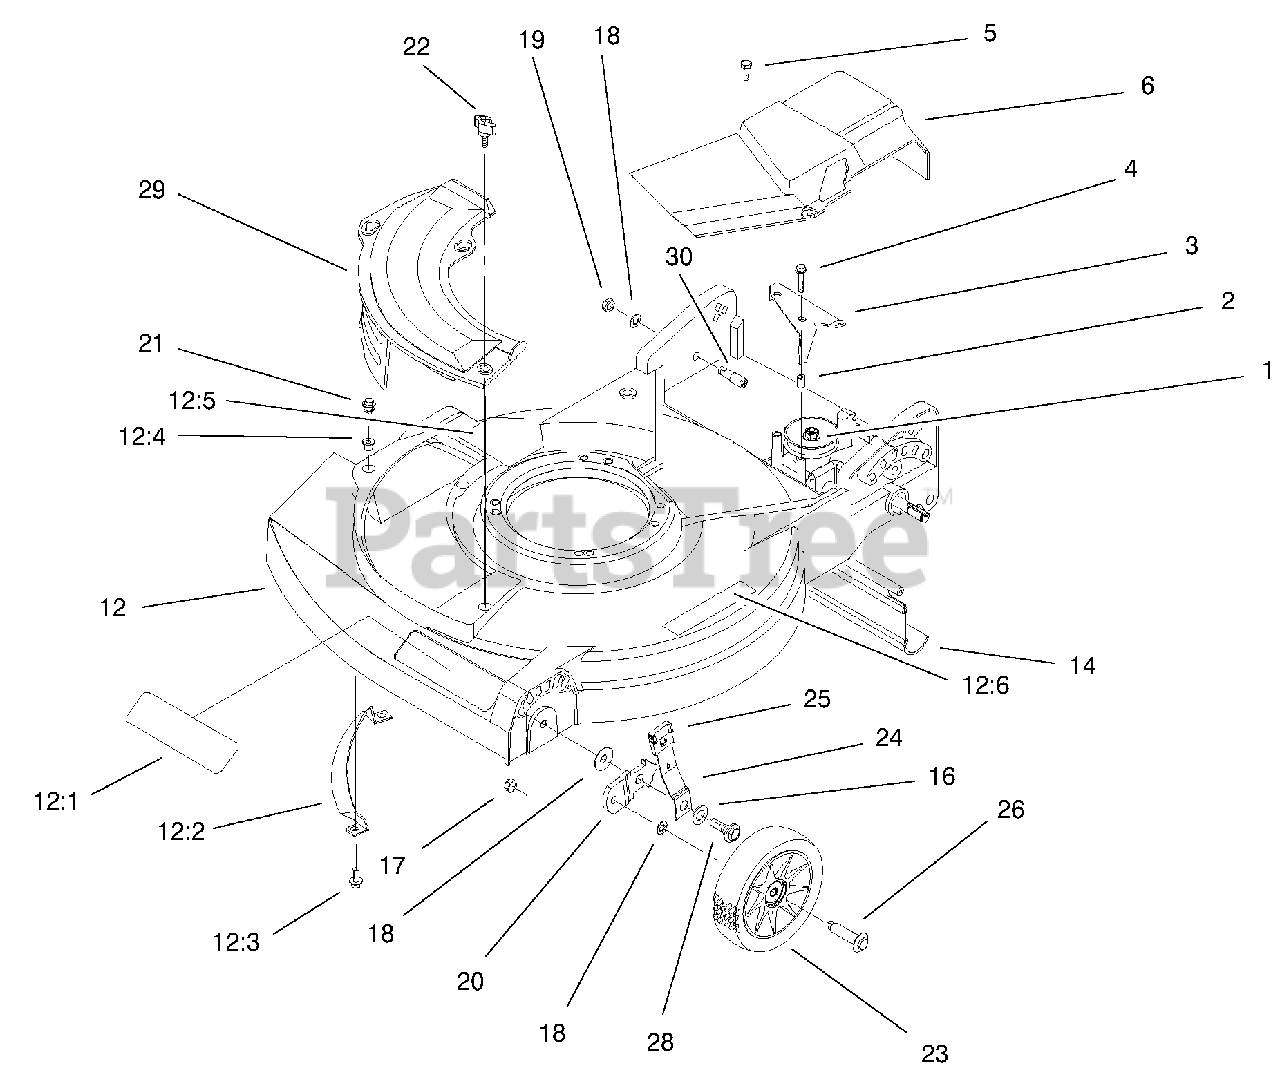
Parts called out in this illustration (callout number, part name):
1	Gear Case ASM
3	Bracket-Actuator
4	Screw-HWH
6	Cover-Drive
12:1	Decal-Deck
12:2	Toe Bar
12:3	Screw-HWH
12:4	Grommet-Plastic
12:5	Decal-Danger
12:6	Decal-Warning
14	Shield-Trailing
16	Washer-Spring
17	Nut-Lock
19	Nut-Lock
20	Bracket-Wheel Height Adjustment
21	Screw-Sems
23	Wheel & Tire ASM
24	Spring Arm ASM-Front
25	Knob-Lever,Height Adjustment
26	Bolt-Shoulder
28	Bolt-Shoulder
29	Plate-Mulch
30	Screw-Torx
